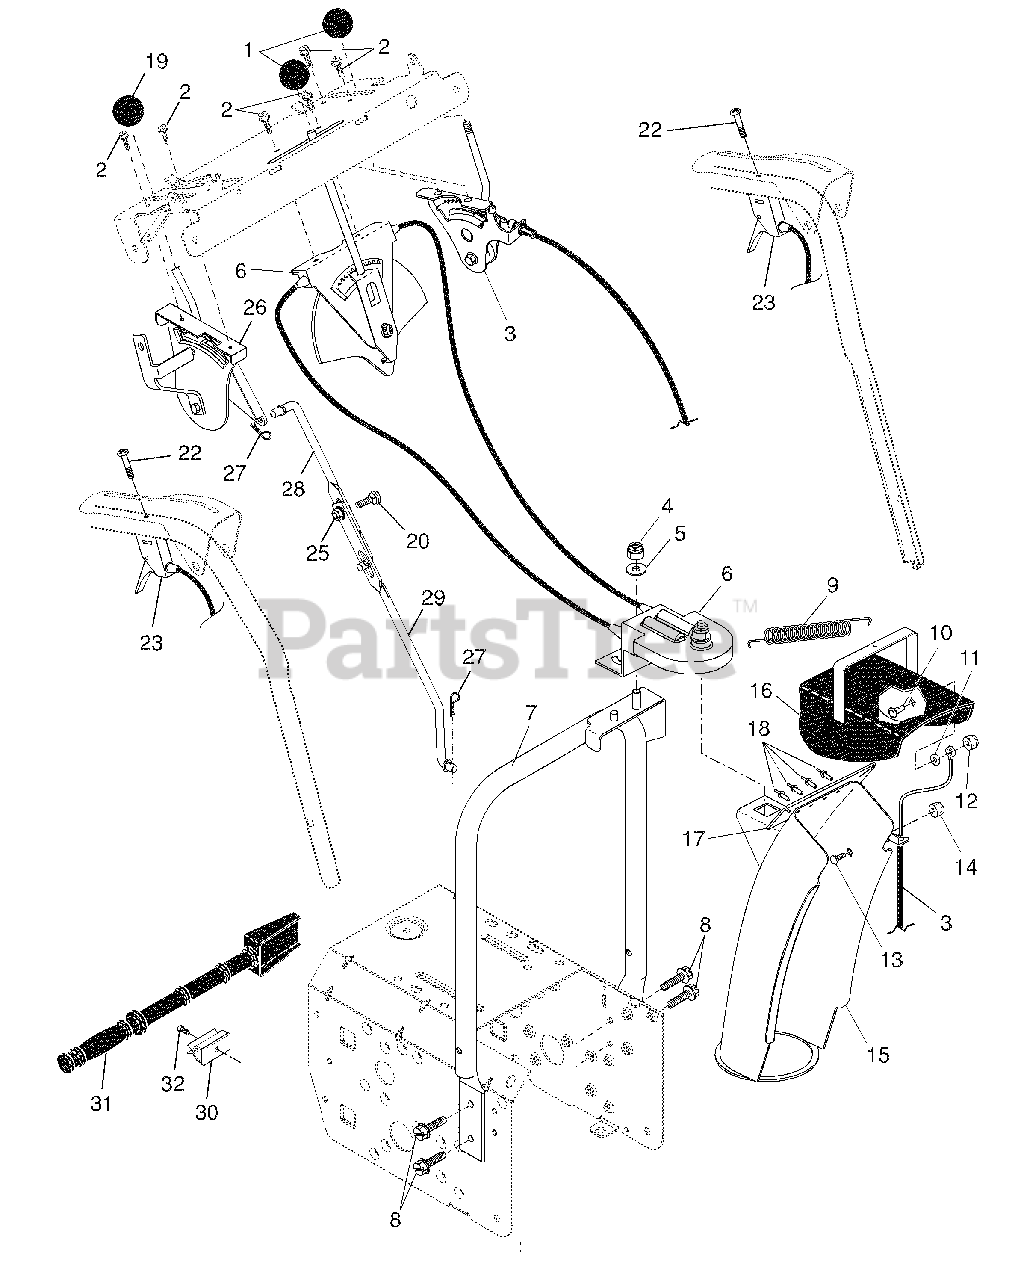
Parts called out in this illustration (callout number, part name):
1	Knob, Lever
2	Screw #10-24 x 5/8
3	Control Assembly, Deflector
4	Nut, Lock 3/8-16
5	Washer, Flat 3/8
6	Control Assembly, Chute Rotater
7	Support, Pivot
8	Screw, Hex Head 5/16-18 x 3/4
9	Spring, Deflector
10	Bolt, Shoulder
11	Washer, Friction, Nylon
12	Nut, Lock 1/4-20
13	Bolt, Carriage 5/16-18
14	Nut, Lock 5/16-18
15	Chute Assembly
16	Deflector Assembly
17	Seal, Deflector
18	Rivet, Blind
19	Knob, Speed Control Lever
20	Bolt, Carriage 5/16-18 x 3/4
22	Screw #10-24 x 1-1/2
23	Control Assembly, Power Steering
25	Nut, Lock 5/16-18
26	Lever Assembly, Speed Control
27	Retainer, Hairpin
28	Rod, Upper, Speed Control
29	Rod, Lower, Speed Control
30	Clamp, Clean-Out Tool
31	Tool, Clean-Out
32	Screw HI-LO 13-16 x 5/8
